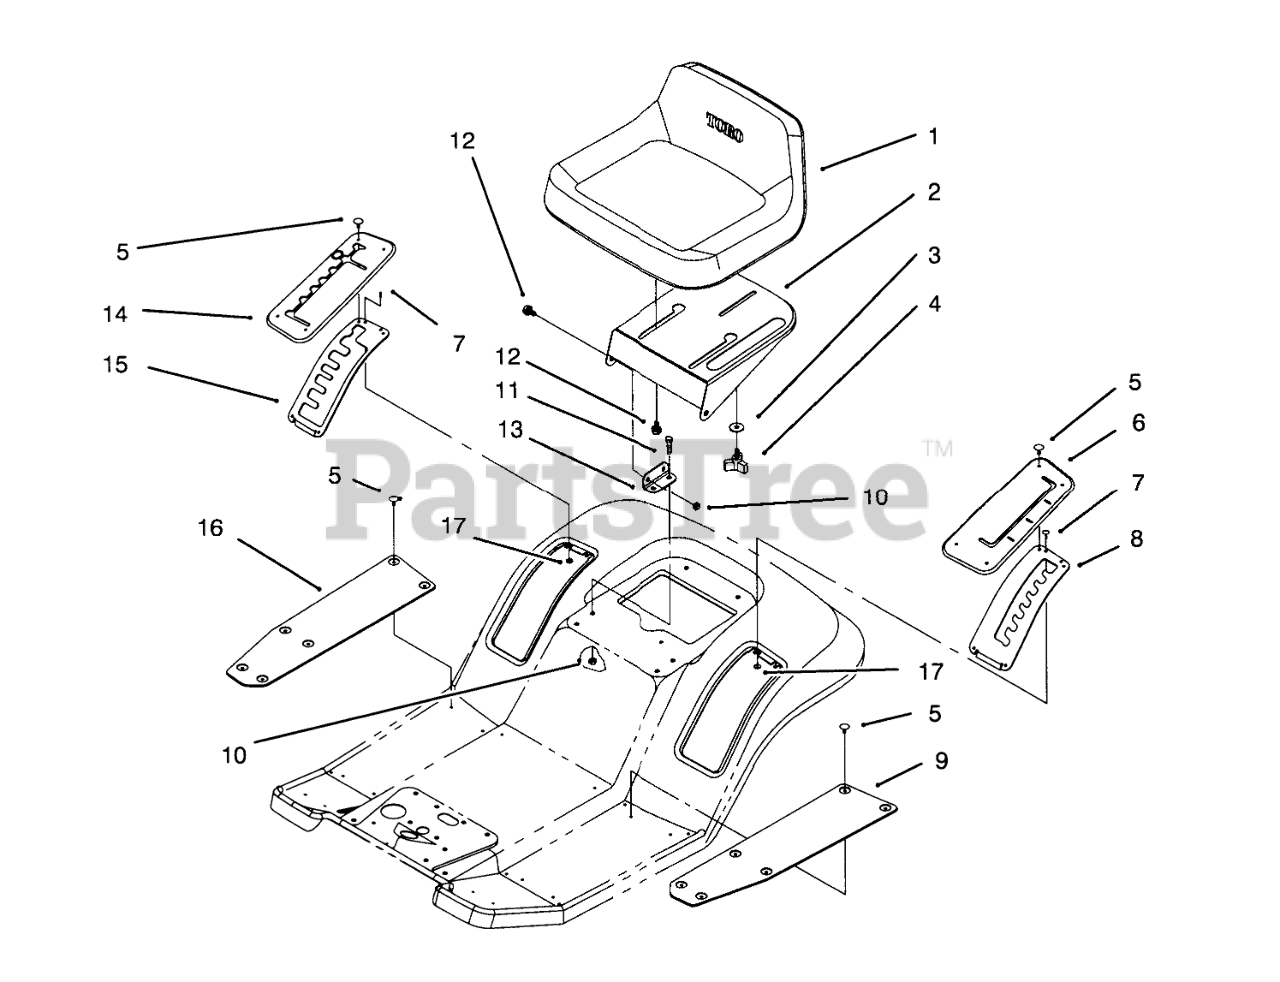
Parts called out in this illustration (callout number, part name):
1	SEAT
2	Support-Seat
3	WASHER-PIVOT
5	FASTENER-PANEL
6	COVER-HOC
7	RIVET-BLIND
8	Gate-H.O.C.
9	MAT-FOOT, LH
10	NUT-LOCK, NI
11	SCREW-HH
12	BOLT-SHOULDER
13	Bracket-Seat Hinge
14	COVER-GATE, SHIFT
15	Gate-Shift
16	MAT-FOOT, RH
17	WASHER-PLAIN
